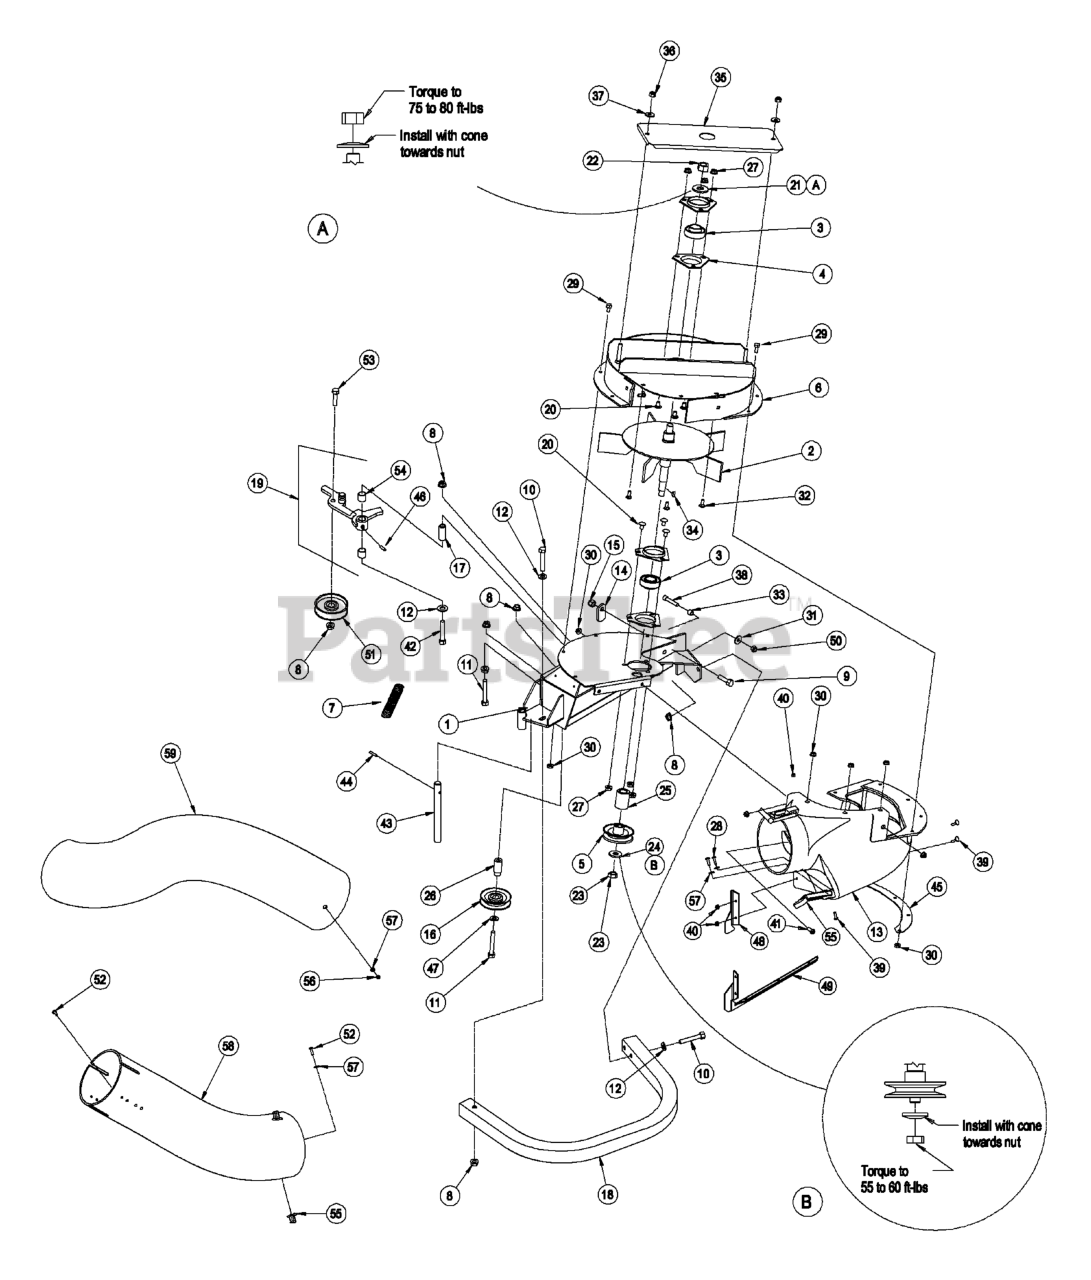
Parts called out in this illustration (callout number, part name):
3	BEARING
4	HOUSING-FLANGE
5	SHEAVE-BLOWER
6	ASM, UPPER HOUSING LZUV52
7	SPRING-IDLER
8	NUT-HHF, WHIZ
9	SCREW-HH
10	SCREW-HH
11	BOLT-CARR
12	WASHER-FLAT
13	CHUTE-BLOWER, SMALL
14	LATCH-CATCHER, GRASS
15	NUT-LOCK, NI
16	IDLER-INSIDE
17	BUSHING-PIVOT, IDLER
19	ASM, IDLER ARM - SERVICE
20	SCREW-CARR
21	WASHER-SPRING
22	NUT-HEX
23	NUT-JAM
24	WASHER-SPRING
28	SCREW-PPH
29	SCREW-HH
31	WASHER-SPRING
32	SCREW-CARR
33	BUSHING, LOCATOR
34	KEY-WOODRUFF
35	ASM, BEARING COVER
36	NUT-LOCK, NI
37	WASHER-FLAT
38	SCREW-HSH
39	SCREW-HEAD, TRUSS
42	SCREW-HSBH
43	SHAFT-CATCHER, GRASS
44	PIN-ROLL
45	PLATE-BACKING, BLOWER
47	WASHER-FLAT
48	PLATE, FILLER
49	PLATE, BLOCKER
50	NUT-HEX
51	IDLER-FLAT
52	SCREW-PPH
53	SCREW-HH
54	BUSHING
55	LATCH DRAW
56	NUT-LOCK, NI
57	WASHER-FLAT
58	Tube, Lower Lz 52
